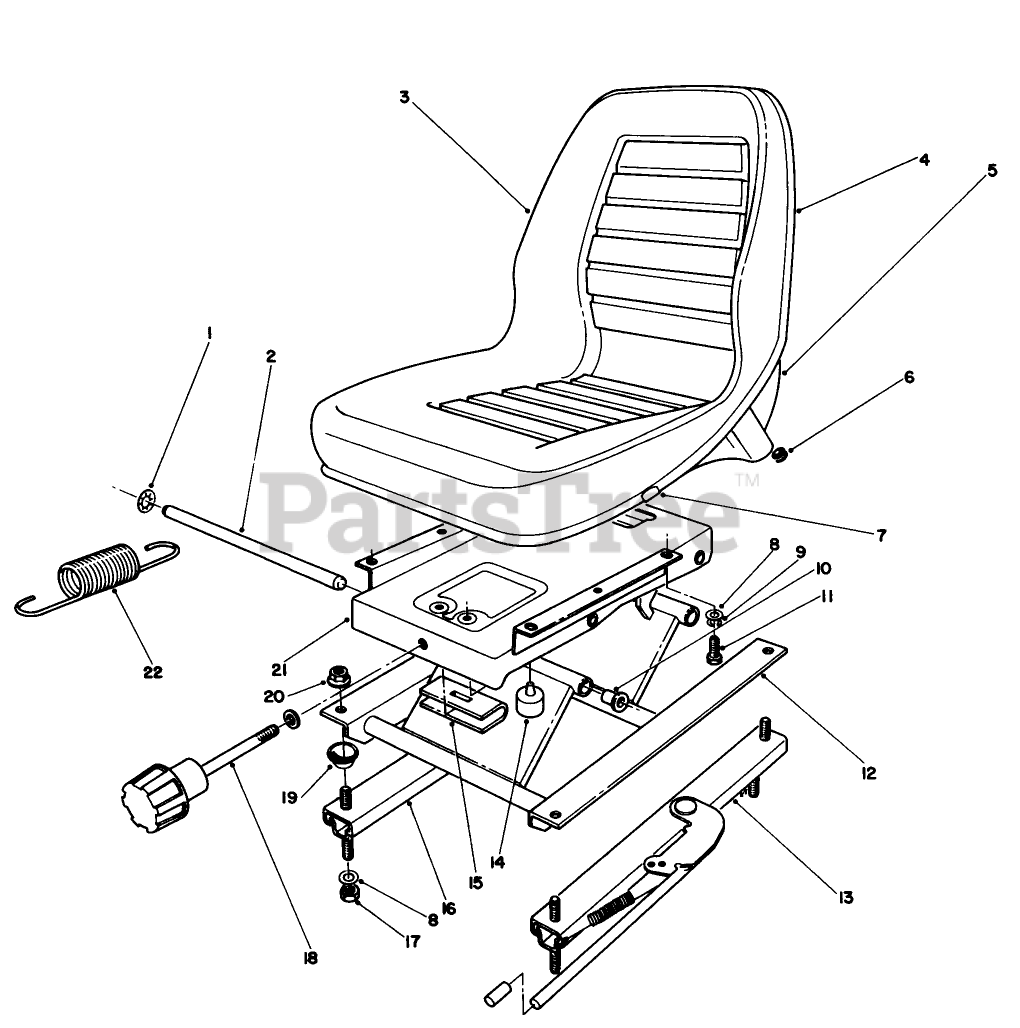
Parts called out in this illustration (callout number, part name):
1	NUT-PUSH
2	Rod-Pivot
3	Cushion-Seat
4	Trim-Seat
5	Base
6	Grommet
7	Cup
8	WASHER-FLAT
9	WASHER-LOCK
10	FLANGE BEARING
11	SCREW-HH
12	FRAME-LOWER
13	ADJUSTER W / HANDLE
14	BUMPER-DOWNSTOP
15	SPRING HANGER
16	ADJUSTER
17	NUT-LOCK, NI
18	Knob-Adjustment
19	SPACER-SUSPENSION
20	NUT-HF
21	FRAME-UPPER
22	Spring-Extension
